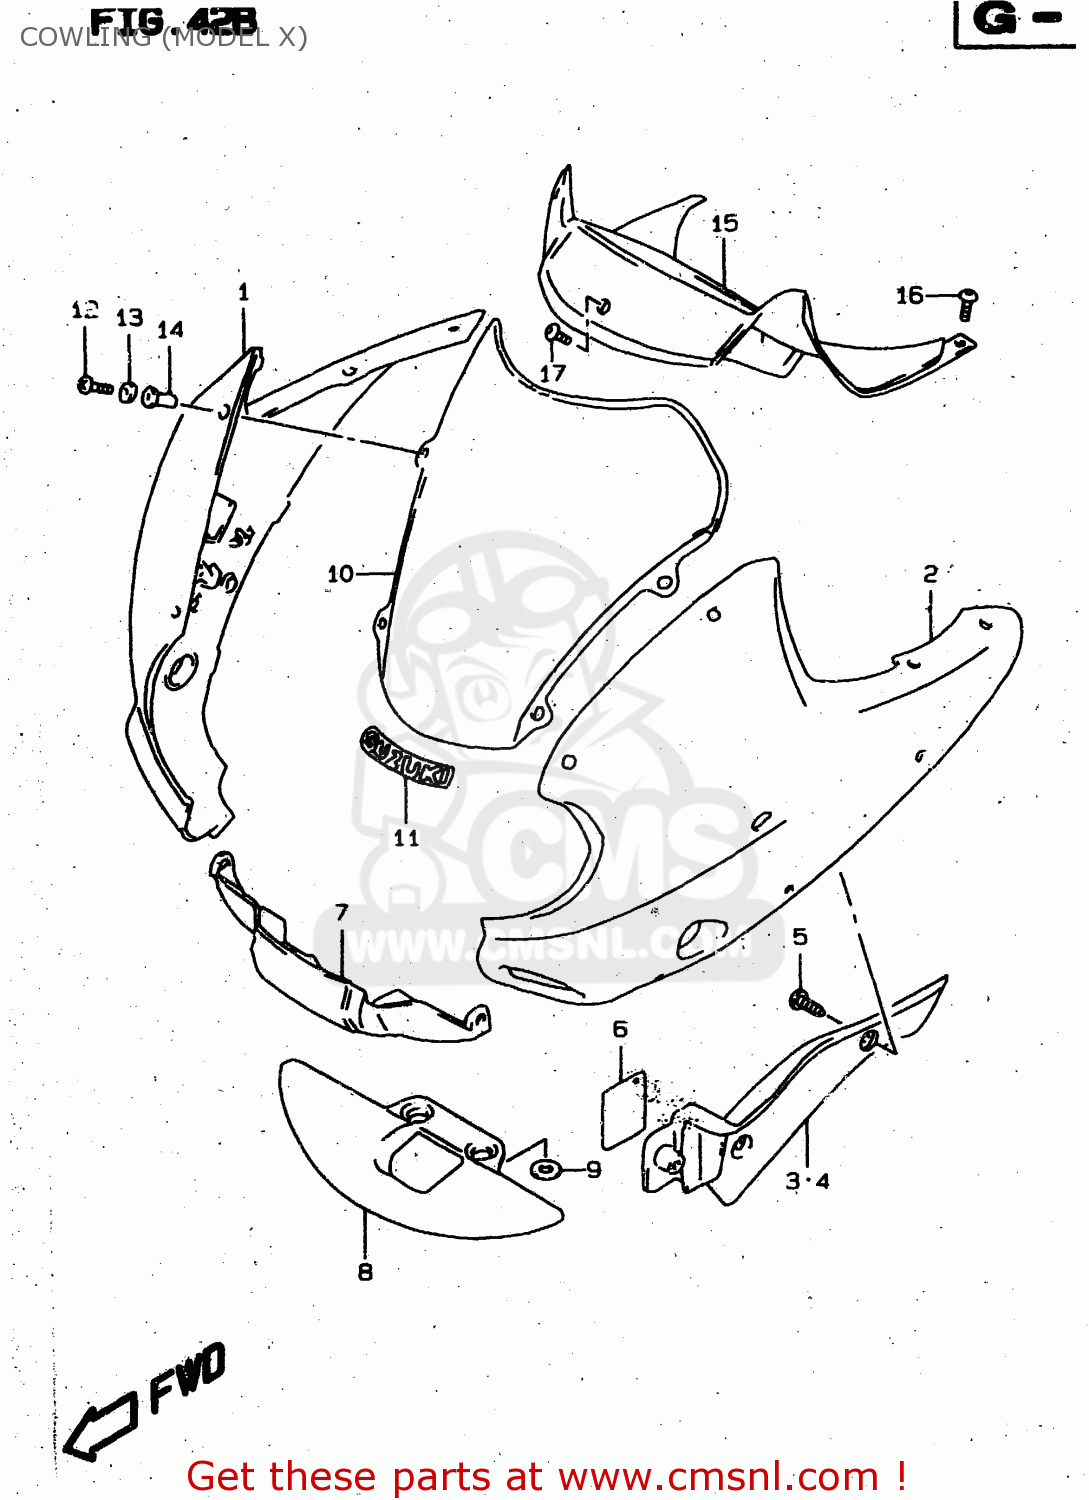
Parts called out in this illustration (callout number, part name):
1	COWLING,SIDE,R
2	COWLING,SIDE,L
3	COVER, SIDE COWL INNER, RH
4	COVER,SIDE COWL INNER,L
5	SCREW 5X10
6	CUSHION,RADIATOR LWR
7	COWLING,CTR
8	COVER,COWLING FR LWR
9	WASHER(6.5X18X1.6)
10	WINDSCREEN(SILVER)
11	EMBLEM,SUZUKI
12	SCREW(5X14)
13	WASHER
14	NUT
15	PANEL,METER
16	SCREW(5X10)
17	SCREW(5X12)
